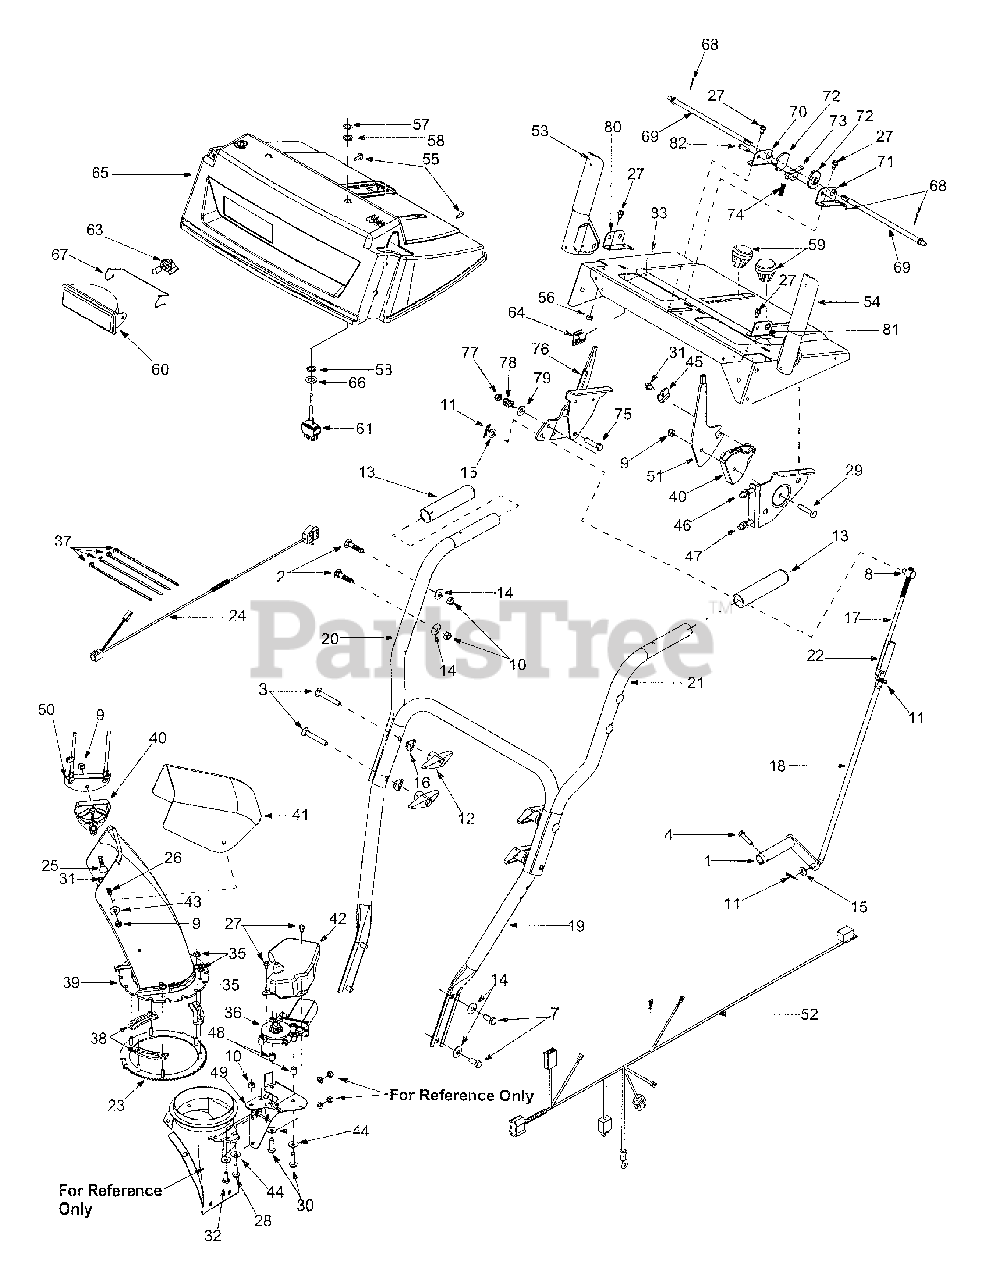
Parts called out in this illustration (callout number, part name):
2	Carriage Bolt 5/16-18 x 1.5"
3	Carriage Bolt 5/16-18 x 2.25"
4	TT Screw 1/4-20 x 1"
7	Hex Screw 5/16-18 x .75"
8	Ferrule
9	Hex Lock Nut 5/16 18
10	Hex Nut 5/16-18
14	Belleville Washer
16	Saddle Washer
17	Shift Rod Upper
18	Shift Rod Lower
23	Gear Assembly Ring
24	Electric Harness Lower
25	Carriage Bolt: 5/16-18 x 1.5"
26	Carriage Bolt: 5.16-18 x .750"
27	TT Screw 1/4-20 x 0.5"
28	TT Screw 5/16-18 x 1"
29	Hex Screw 5/16-18 x 1.5"
30	TT Screw 5/16-18 x 1.25"
31	Hex Screw AB: 1/4-14 x 0.625"
32	Hex Screw. 5/16-18 x .75"
35	Hex Flange Lock Nut
36	Electric Motor: Chute Crank
38	Chute Flange Keeper
39	Lower Chute
40	Cable Guide: Chute Tilt
41	Upper Chute
42	Motor Cover: Chute Rotation
44	Belleville Washer
45	Special Washer
46	Control Cable
47	Control Cable
52	Harness Assembly: Upper
53	Handle Assembly RH
54	Handle Assembly LH
55	Special Hex Screw
56	Hex Sems Nut: 1/4-20
58	Lock Ring: Toggle Switch
59	Shift Knob
60	Lamp Housing
61	Toggle Switch: Double Throw
63	Halogen Lamp: 50W, 12V
64	Mounting Clamp
65	Handle Panel
66	Flat Washer
67	Headlight Retainer
68	Cotter Pin: 3/32 x .75
72	Cam Handle Lock
73	Handle Lock Pawl
74	Compression Spring: .36 x 1 0
75	Hex Cap Screw: 3/8-24 x 1.5
78	Comp Spring: .39 x .6 x .88
